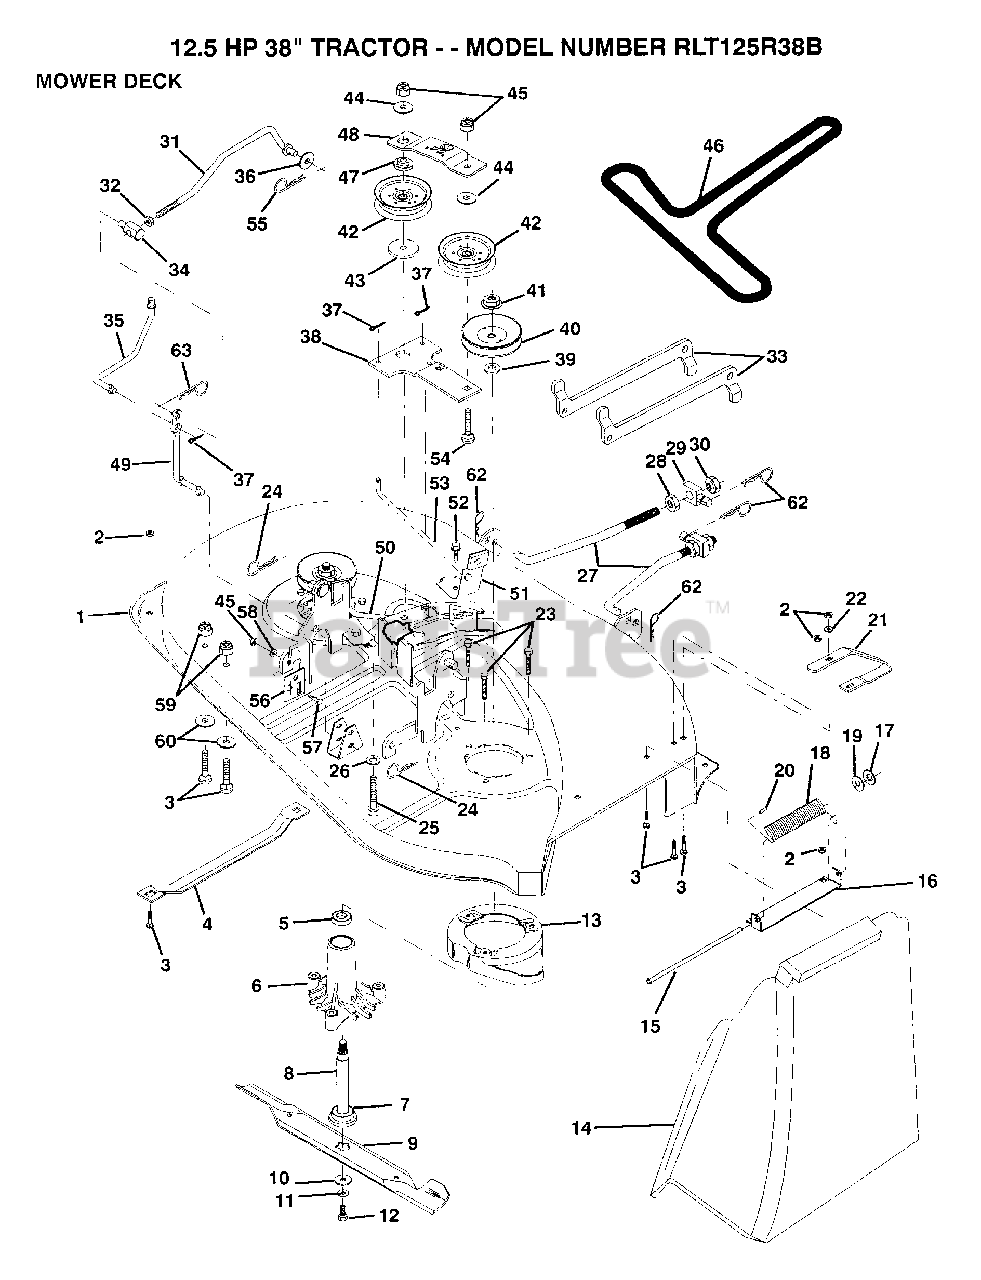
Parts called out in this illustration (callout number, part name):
3	BOLT
4	RUNNER-LH M
5	BEARING
6	HSG ASM MANDREL
7	BEARING.BALL
9	"BLADE.38"" HIPERF"
10	WASHER BLADE
12	BLADE BOLT
14	DEFLECTOR-SHLD T
15	ROD-HINGE T
16	BRKT DEFLECTOR
17	NUT PUSH M
18	SPRING TORSION
19	WASHER
20	CAP-SLEEVE LT
21	RUNNER RH
22	WASHER M
25	BOLT
26	WASHER GT
27	"LINK ASM.,FRONT"
28	NUT
29	TRUNION
30	NUT.LK.W/WSH.1/2.
31	CLUTCH ROD PRI
32	NUT
33	SUSP ARM REAR
34	TRUNNION
35	CLUTCH ROD SEC
36	WASHER
38	IDLER ARM ASSY
39	WASHER
42	FLAT IDLER PULLEY
43	SPACER RETAINER
44	WASHER GT
46	BELT-V.88.12.MW
47	RETAINER SPACER
48	IDLER ARM STIFF
49	PIVOT ROD
50	BRAKE ROD LH
51	BRAKE ASM
52	SCREW
53	BRAKE ROD RH
54	BOLT
55	SPRING.RETAINER
56	PLATE ADJ LINK LH
57	BOLT
58	WASHER T
59	NUT
60	WASHER.34X.68X16
62	RETAINER.SPRING
63	RETAINER M
